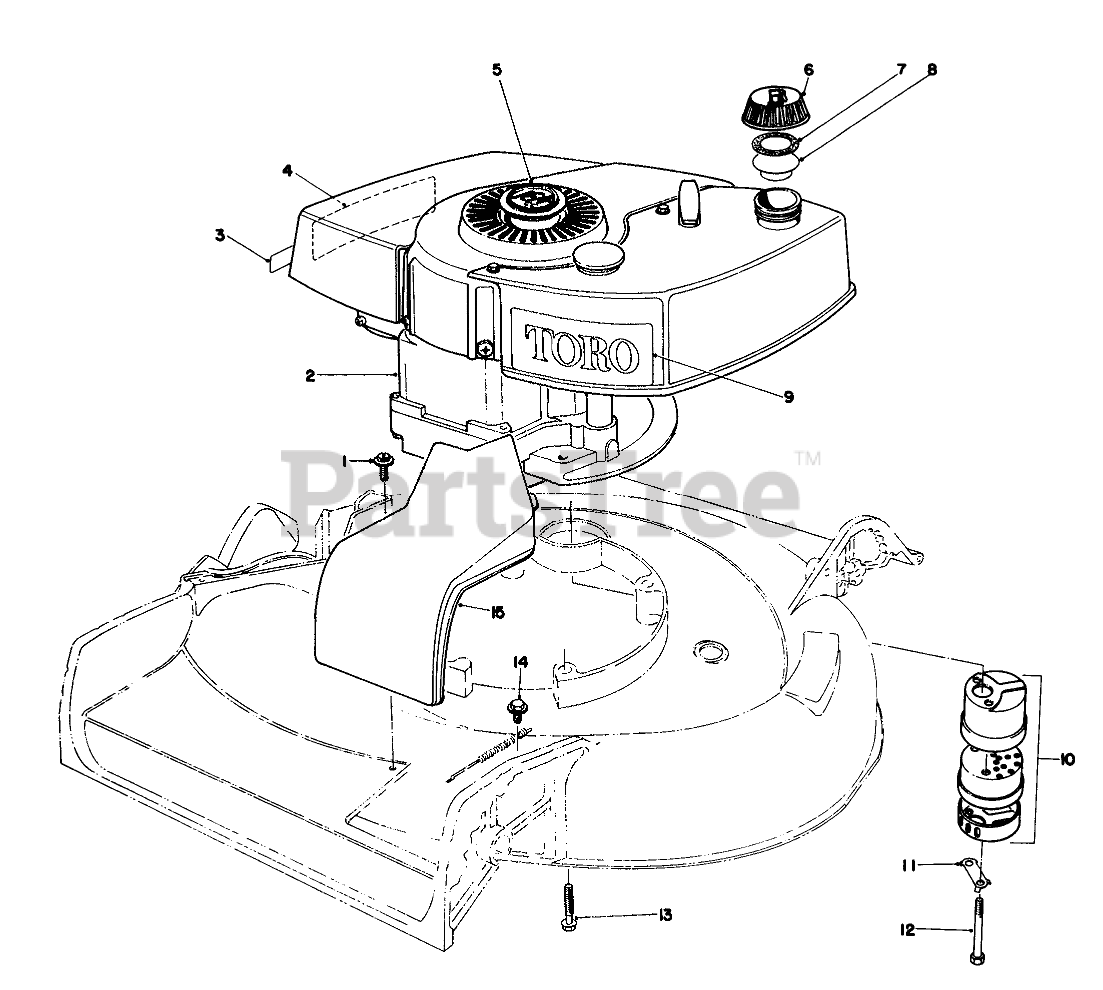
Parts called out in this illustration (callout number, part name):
1	SCREW
2	Engine
3	Decal-Primer Bulb
4	Decal Maintenance
5	Plug Button
6	Gas Cap Assembly (Incl. Ref. #7 & 8)
7	GASKET
8	GAS CAP BAFFLE
9	Decal Toro
10	Muffler (Incl. Ref. #11 & 12)
11	CLIP - LOCKING
12	SCREW-HH
13	3/8-16 X 2-3/4 CAPSCR
14	SCREW-HWHTF
15	Cover-Belt Drive
